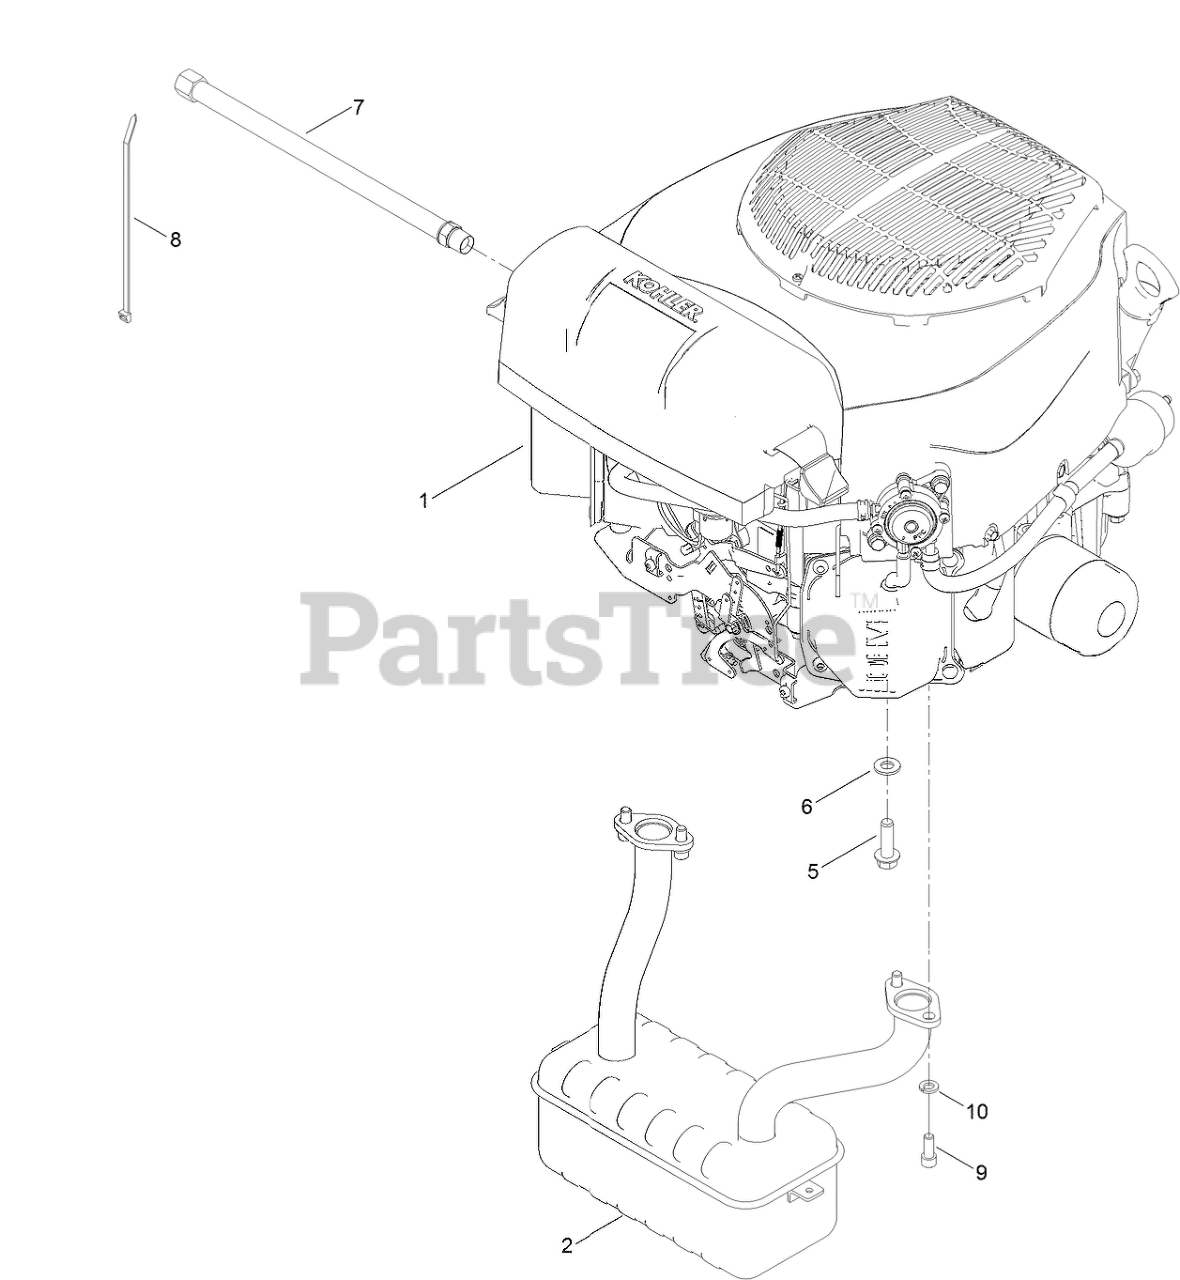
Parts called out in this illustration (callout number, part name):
2	MUFFLER
5	SCREW-THD
6	WASHER-FLAT
7	HOSE-DRAIN, OIL
8	TIE-CABLE
9	SCREW-HSH
10	WASHER-LOCK
